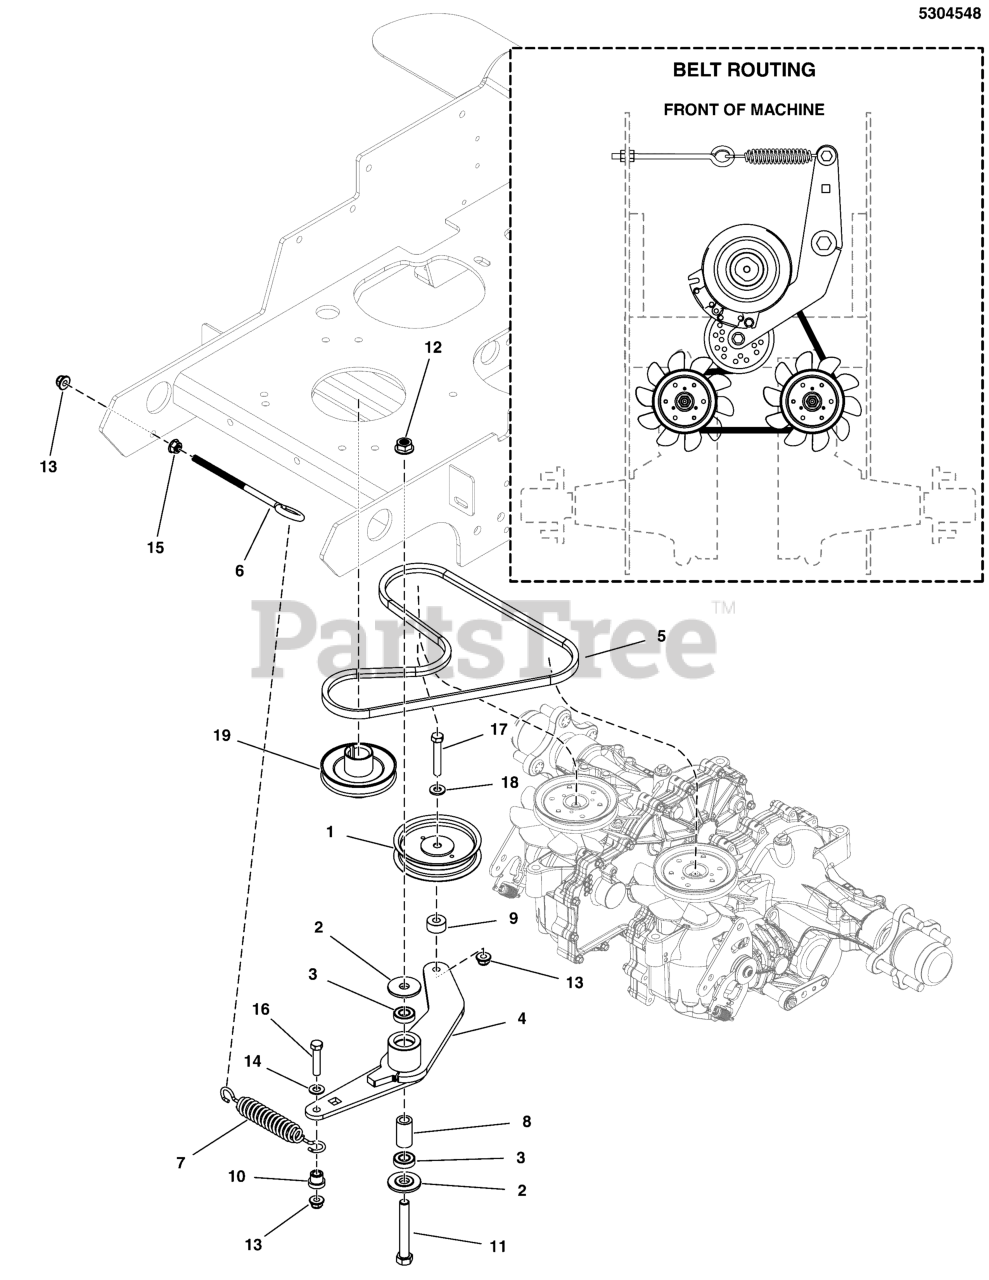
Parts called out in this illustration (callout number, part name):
1	PULLEY-IDLER 04.00 OD 0.378ID 1.06 W BRG
2	SPACER, IDLER ARM, 1/2, PM
3	BEARING, BALL, AXLE
4	WELD, IDLER ARM, PUMP DRIVE - BLK
5	BELT, A-SEC, 50.5"EL, RAW EDGE, COG
6	EYE BOLT, 3/8-16 X 6, 3THRD, 1EYE, CZ
7	SPRING-EXT, 1.04 ODX6.935LGX.148WR, BLK
8	SPACER, .52 X .84 X 1.53, PM
9	SPACER, .39 X 1.00 X .50, PM, CZ
10	BUSHING, .38 X .88 X .73
11	BOLT, 1/2-13 X 3-1/2, HEX HD, GD5, CZ (SV)
12	NUT, Hex Flange, Nylock, 1/2-13
13	NUT, 3/8 - 16 HEX NYLOCK FLANGE
14	WASHER, 3/8 SAE
15	NUT, 3/8-16 Hex Large Serrated Flange
16	BOLT, 3/8-16 X 1-3/4" GD5 CZ
17	HHCS, 3/8-16 X 2.00, GR5, ZINC/CLEAR
18	WASHER, 3/8" GR. 9 FLAT
19	PULLEY, CRANKSHAFT (SEE ENGINE & PTO GROUP)
